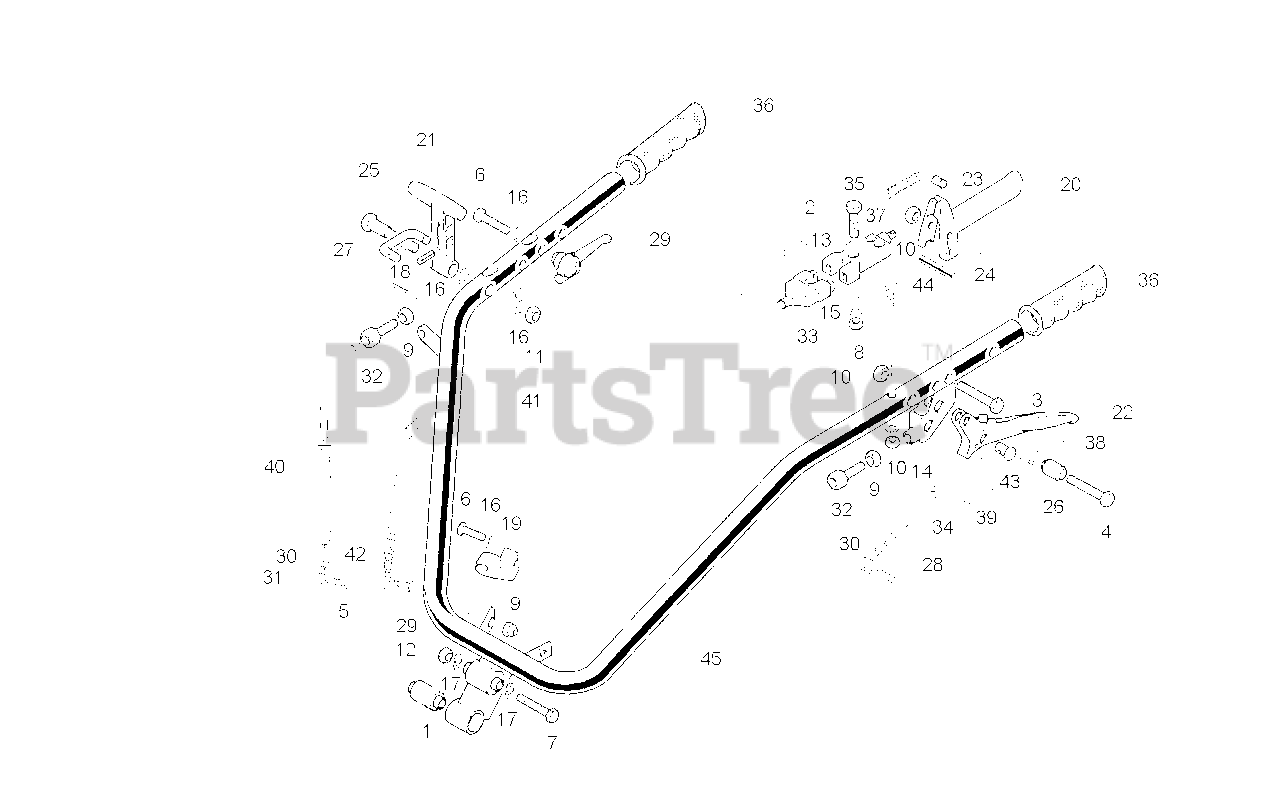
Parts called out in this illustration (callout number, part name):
1	SILENTBLOCK
2	SCREW TE M4X25
3	SCREW, TE M6X45
4	SCREW, M6X25
5	SCREW, TE M6X16
6	SCREW, M8X35
7	SCREW, M10X80
10	NUT, SELF LOCKING M6
13	FLAT WASHER, M4.3
14	WASHER, FLAT M6.3
15	LOCK WASHER, M4.3
16	LOCK WASHER, M8.4
17	WAVE WASHER, M10.4
18	PIN, LOCKING, M4X20
19	SUPPORT, CONTROL ROD
20	MOTOR STOP LEVER
21	REVERSER LEVER
22	CLUTCH LEVER
24	LEVER STOP FOR MOTOR STOP
26	LEVER SPACER
28	CLAMP, CABLE
29	LEVER, ACCELERATOR
31	PIN, CABLE CLAMP
32	SCREW, ADJUSTING, M8
33	SWITCH WIRING HARNESS
34	CLUTCH CABLE
37	STOP SWITCH
38	LEVER SPRING
40	REVERSER CABLE
41	THROTTLE CABLE
42	CABLE ADJUSTER
44	SWITCH PLATE
